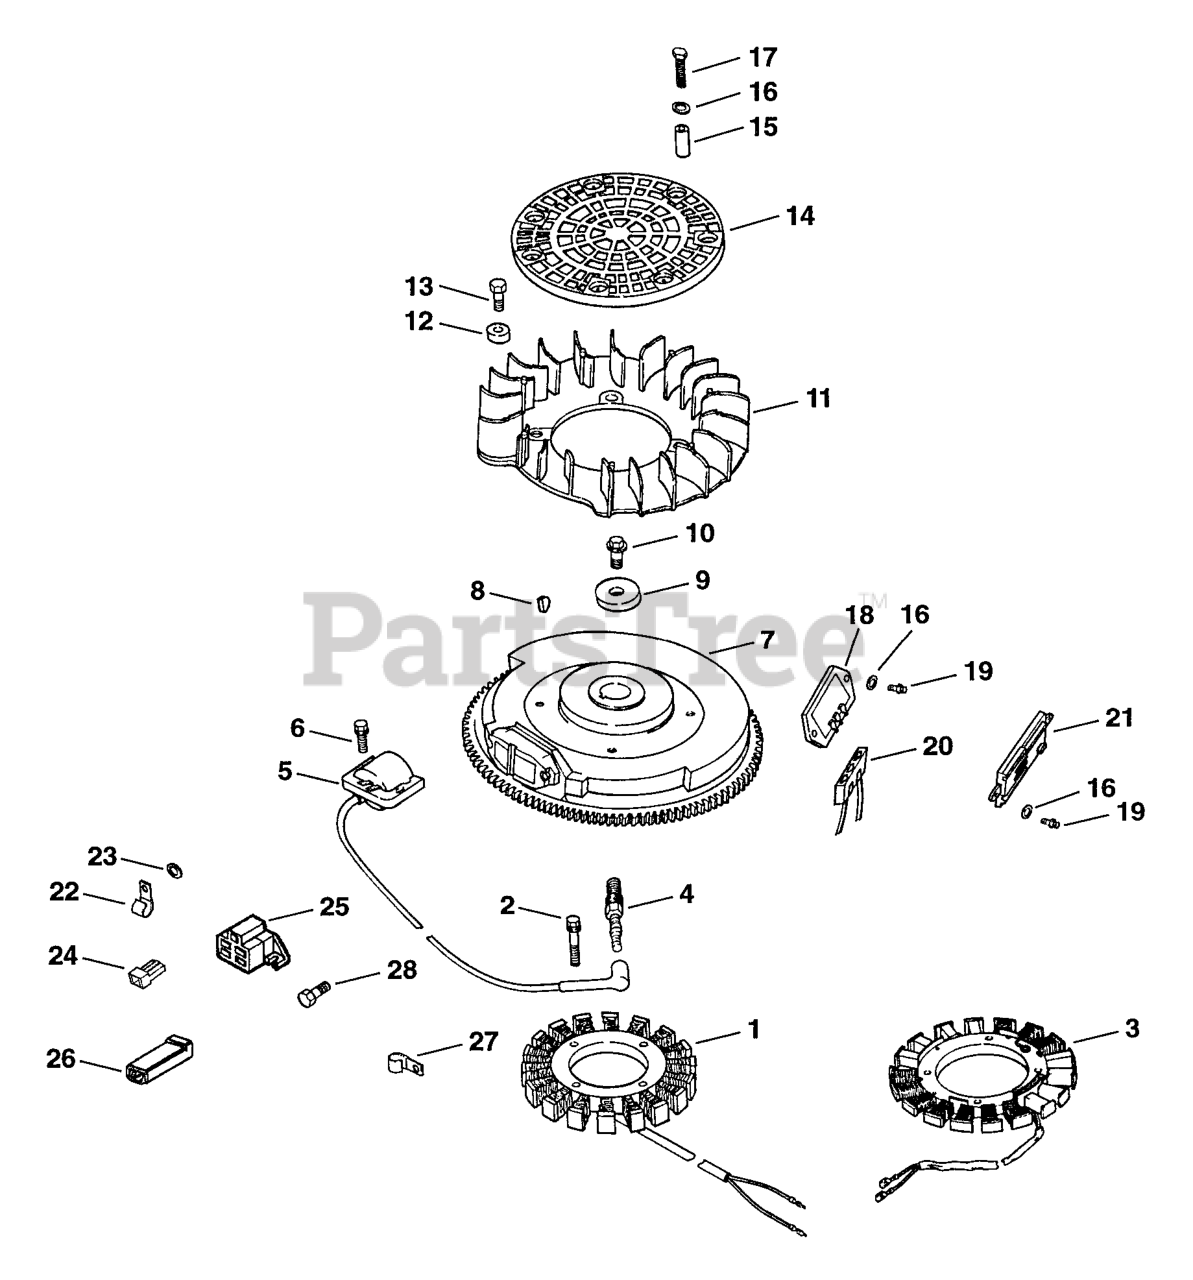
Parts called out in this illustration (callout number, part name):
1	Stator (15 Amp)
2	Screw, Hex. Cap M5x0.8x25
4	Spark Plug
7	Flywheel
9	Washer, Plain 3/8"
10	Screw, Hex. Flange M10x1.5x76
16	Washer, Plain 1/2"
18	Rectifier-Regulator
19	Screw, Hex. Flange M10x1.5x61
20	Connector (3 Contact)
23	Washer, Plain 1/4"
